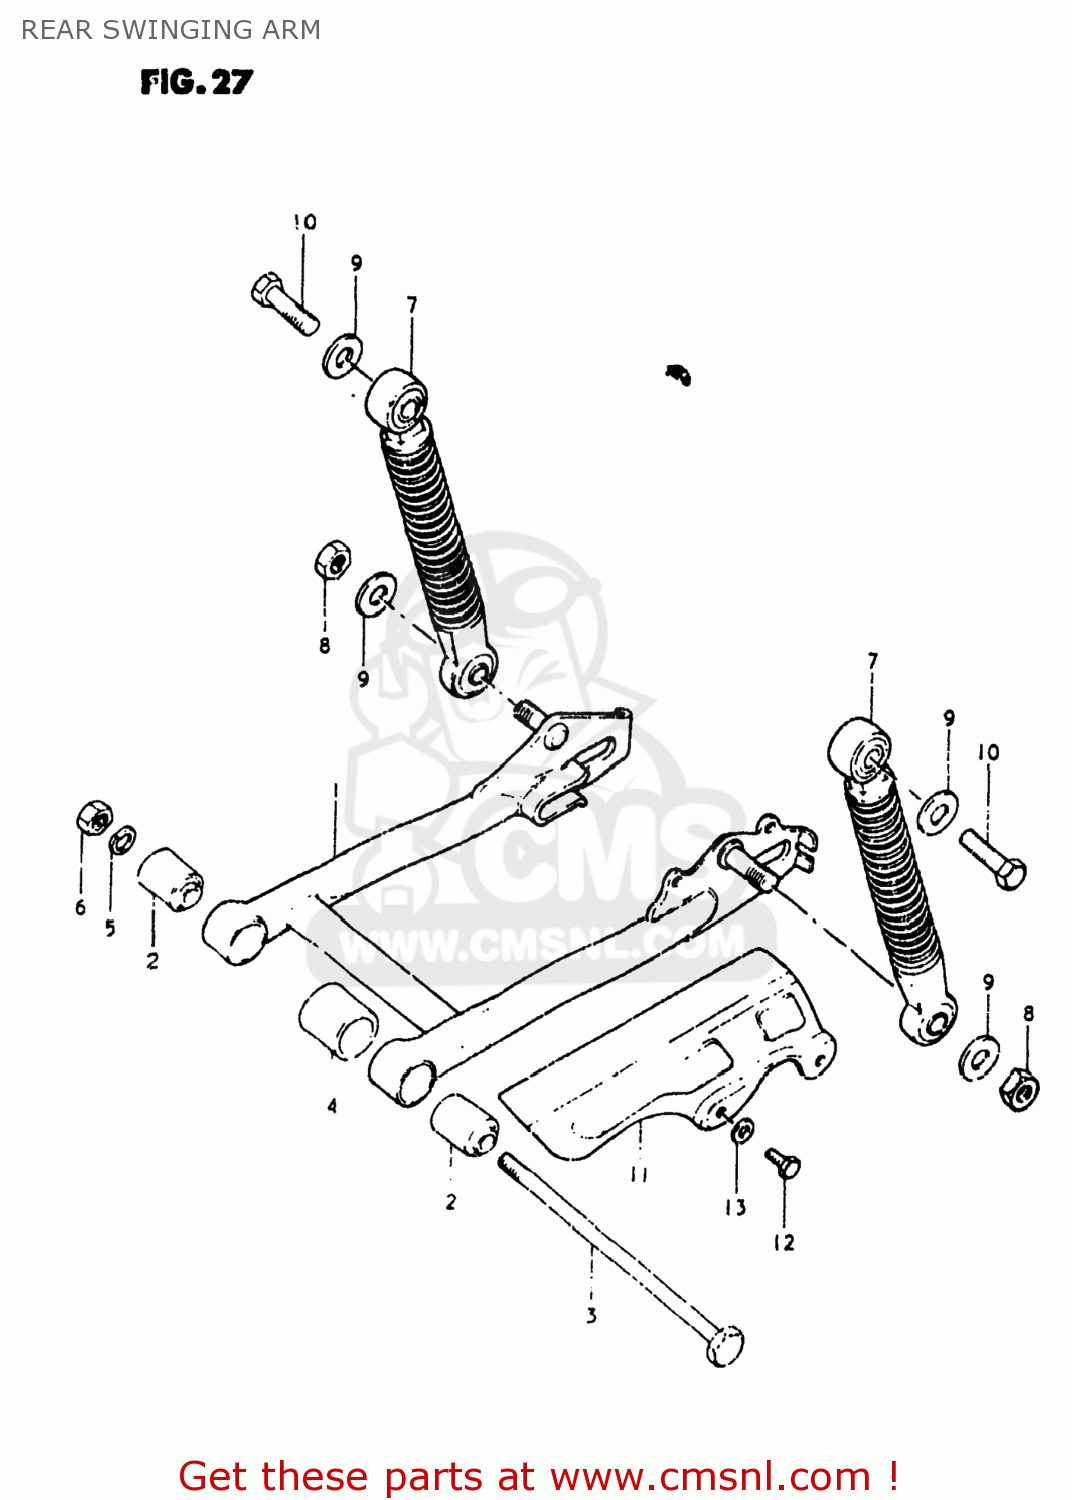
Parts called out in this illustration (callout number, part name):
1	SWING ARM ASSEMBLY,REAR
2	BUSH
3	SHAFT,RR SWINGINGARM PIVOT
4	CUSHION
5	LOCK WASHER
6	NUT
7	ABSORBER ASSY,RR SHOCK
8	NUT
9	WASHER
10	BOLT,M10X1.25X
11	CASE,CHAIN
12	BOLT
13	LOCK WASHER
